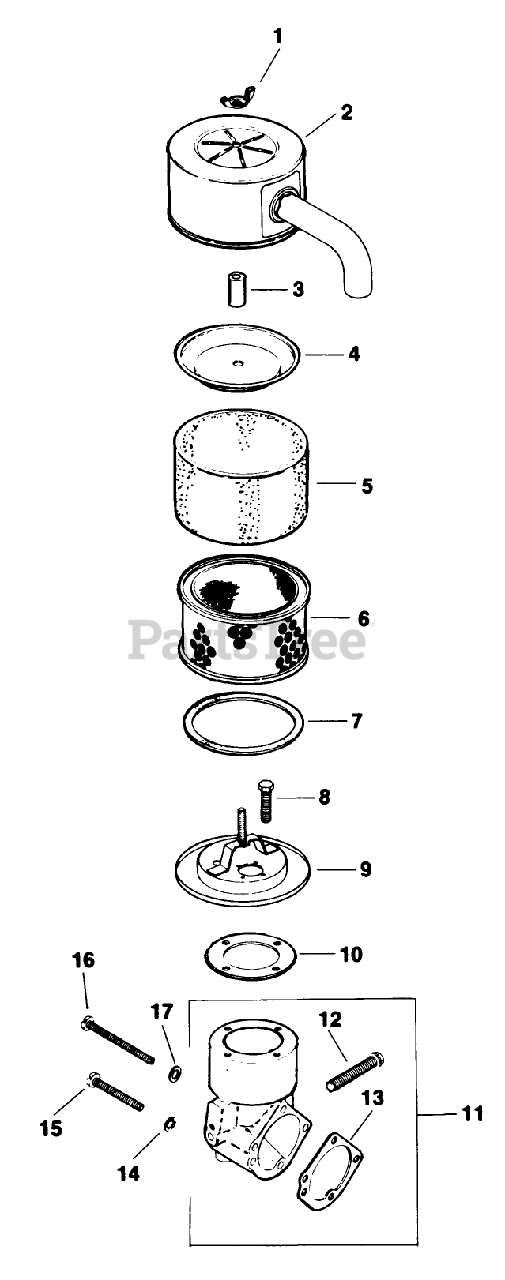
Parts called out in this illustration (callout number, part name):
1	Nut-Wing
2	Cover-Air Cleaner
3	Seal
4	Cover-Inner
5	Element
6	Element
7	Seal
8	Screw-H.C.
9	Base-Air Cleaner
10	Gasket-Air Cleaner
11	Kit-Elbow (Incl. Ref. #12 & 13)
12	Screw-H.C
13	Gasket-Elbow
14	Washer
15	Screw-R.H.M.
16	Screw-R.H.M.
17	Washer
